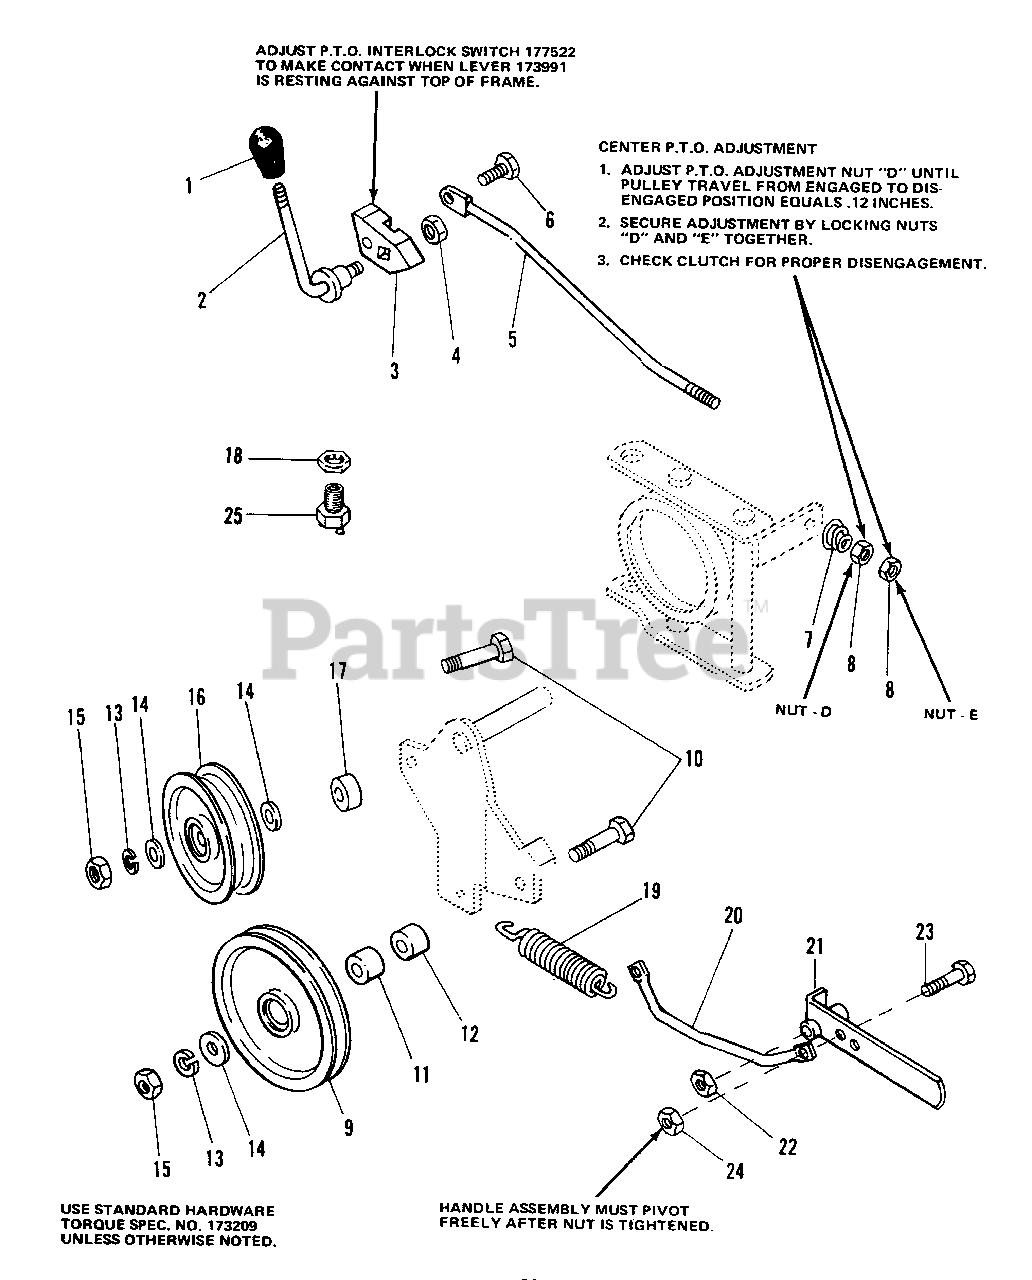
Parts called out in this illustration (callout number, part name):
1	KNOB
2	HANDLE, Clutch P.T.O.
4	LOCKNUT, Hex, 3/8-16
5	CONTROL ROD ASSEMBLY
6	CAPSCREW, Special
8	NUT, Hex, Full, 5/16-18
10	CAPSCREW, Hex Hd., 3/8-16 x 2
13	LOCKWASHER, 3/8
14	WASHER, 5/16
15	NUT, Hex, Full, 3/8-16
16	PULLEY- Double
18	NUT, Pal
19	SPRING, Tension
20	ROD, Tension
21	HANDLE ASSEMBLY
22	LOCKNUT, Hex, 7/16-14
23	CAPSCREW, Hex Hd., 5/16-18 x 3/4
24	LOCKNUT, Hex, 5/16-18
25	SWITCH, Interlock
